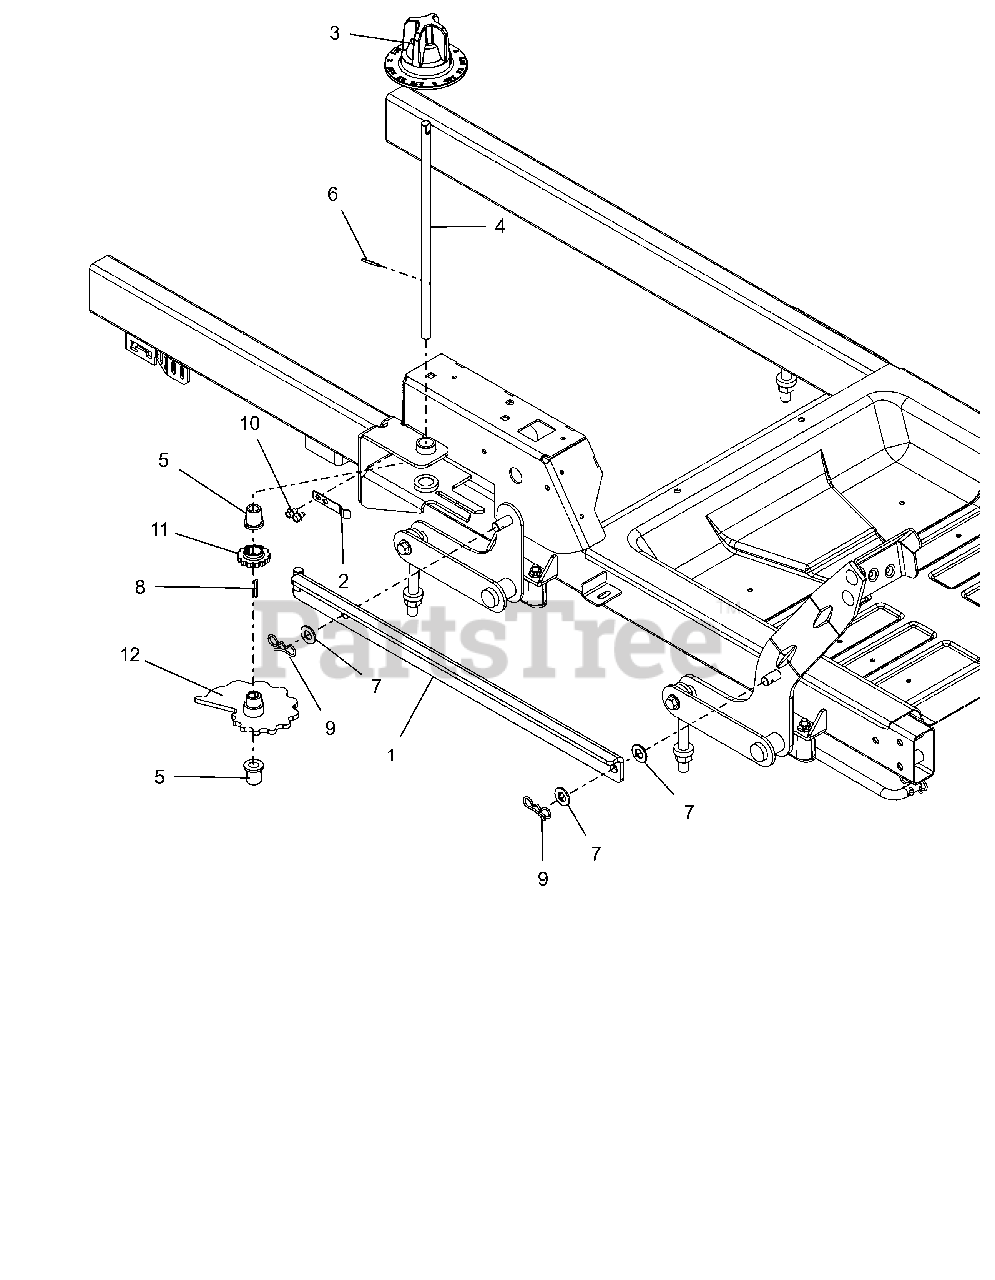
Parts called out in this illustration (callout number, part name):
1	WLDMT, HOC LINK
2	ARM, HOC DETENT
3	KNOB, HOC DIAL
4	SHAFT, HOC CAM
5	BSHG-FLG, .503X.750X.875X1.00
6	PIN-ROLL .125X1.00
7	WSHR-FL-NYL .518X1.000X.080
8	KEY, 1/8 X 1/8 X 1.0
9	PIN,BOW TIE LOCKING .091X1.875
10	SCR,TAP .25-20X.375 HWH TR ZCC
11	GEAR, HOC INDEX
12	WLDMT, HOC CAM
